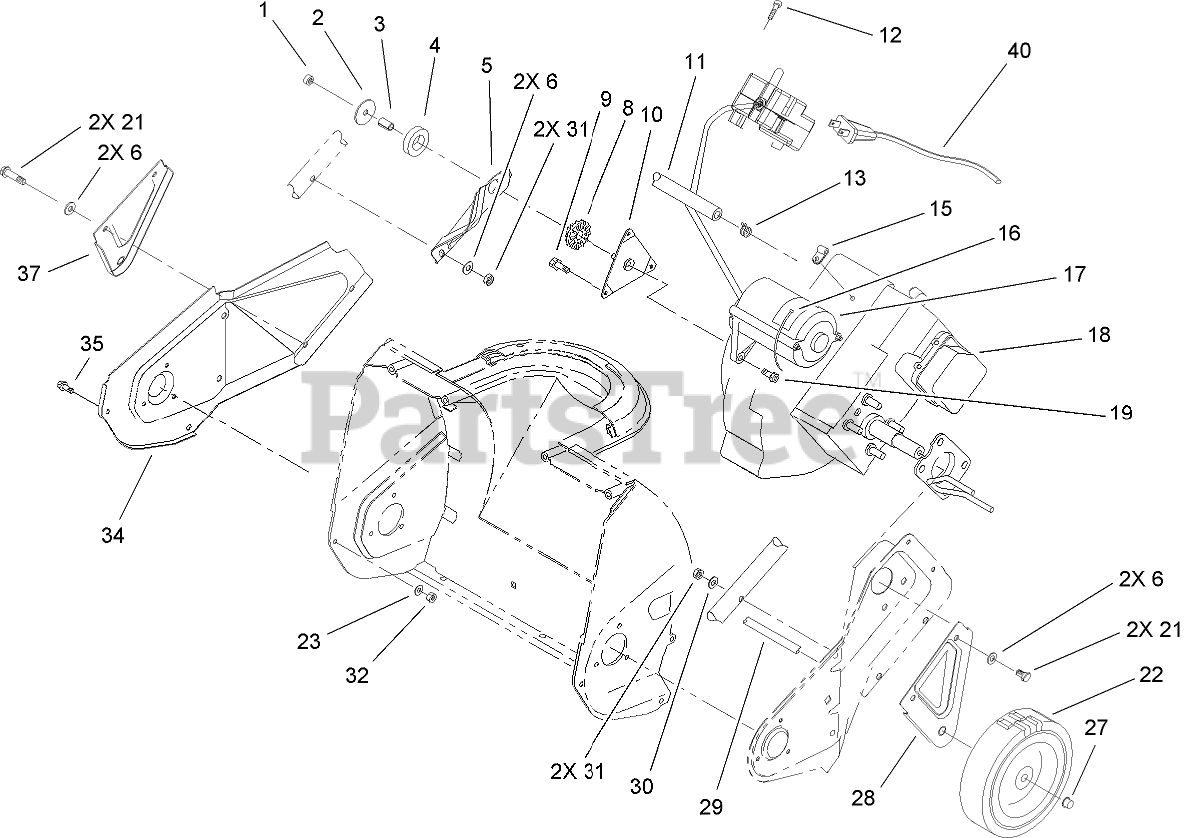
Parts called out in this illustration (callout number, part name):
1	NUT-LOCK, NI
2	WASHER-FLAT
3	SPACER-TUBULAR
4	RING-ISOLATOR
5	BRACKET-SUPPORT, ENGINE
6	WASHER-FLAT
8	BUSHING-ISOLATOR
9	SCREW
10	BRACKET AND STUD ASM
11	HOSE-FUEL
12	SCREW-PLASTITE
13	CLAMP-HOSE
15	CLAMP
16	TIE-CABLE
17	120 VOLT STARTER ASM
19	SCREW-HH, TORX
21	SCREW-HH
22	WHEEL
23	WASHER-FLAT
27	RETAINER-PUSH ON
28	BRACKET-WHEEL, LH
30	WASHER
31	NUT-LOCK, NI
32	NUT-LOCK, NI
34	PLATE-SIDE, RH
35	SCREW-PLASTIC
37	BRACKET-WHEEL, RH
40	CORD-ELECTRIC
